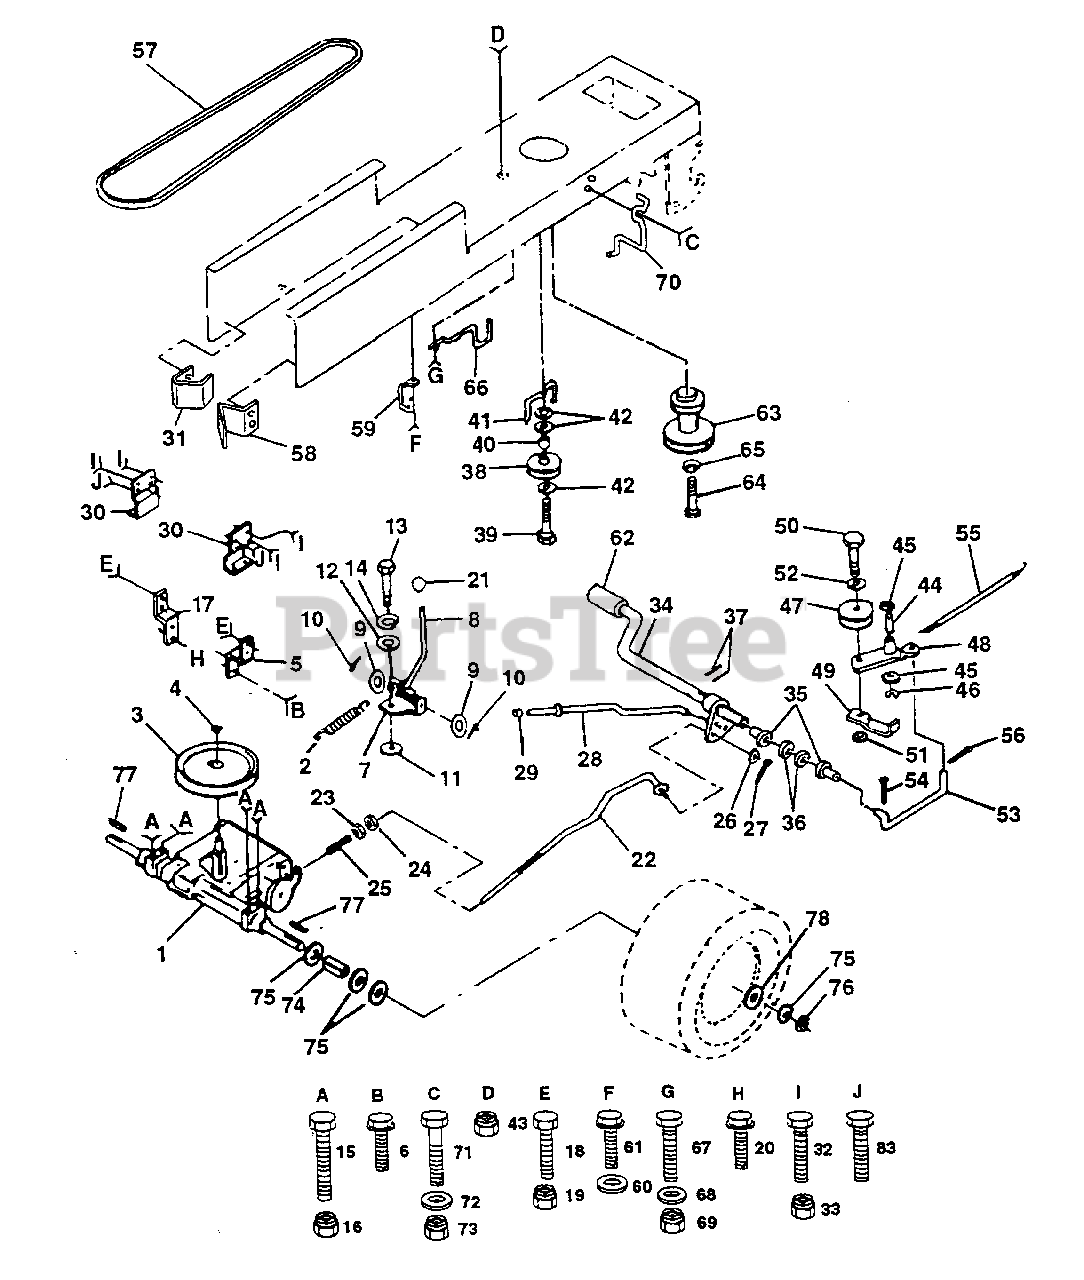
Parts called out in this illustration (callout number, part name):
1	Transaxle 6sp Dana LT Model No 4360-48 (AYP part number)
2	Spring Return Brake T/a Zinc (AYP part number)
3	Pulley Transaxle 18"tires (AYP part number)
4	Ring Retainer # 5100-62 (AYP part number)
5	Strap Torque 30 Degrees (AYP part number)
6	Screw Thdrol 5/16-18 X 3/4 TYT
7	Plate Rod Shift T/a (AYP part number)
8	Rod Shift Blk (AYP part number)
9	Washer 15/32 X 3/4 X 16 Ga (AYP part number)
10	Pin Cotter 1/8 X 1 Cad (AYP part number)
11	Washer Plate Shf 388 Sq Hole (AYP part number)
12	Washer 9/32 X 3/4 X 10 Ga (AYP part number)
13	Bolt Fin Hex 1/4-28unfx3/4 Gr8 (AYP part number)
14	Washer Lock Hvy Helical 1/4 (AYP part number)
15	Bolt Fin Hex 5/16-18uncx 2-1/2 (AYP part number)
16	Nut Crown Lock 5/16-18
17	Strap Torque 30 Degrees (AYP part number)
18	Bolt Fin Hex 3/8-16unc X 3/4 (AYP part number)
19	Nut Crownlock 3/8-16 Unc
20	Screw Thdrol 5/16-18 X 3/4 TYT
21	Knob Rd 1/2-13 Plstc Thds Blk (AYP part number)
22	Rod Brake LT/YT (AYP part number)
23	Nut Lock Hex W/wsh 3/8-16unc (AYP part number)
24	Nut Hex Jam 3/8-16 Unc (AYP part number)
25	Spring Rod Brake 2 00 Zinc (AYP part number)
26	Washer 13/32 X 13/16 X 16 Ga (AYP part number)
27	Pin Cotter 1/8 X 3/4 Cad (AYP part number)
28	Rod Brake Parking LT (AYP part number)
29	Cap Brake Parking Black (AYP part number)
30	Bracket Transmission (AYP part number)
31	Keeper Belt LH LT 14 Ga (AYP part number)
32	Bolt Fin Hex 5/16-18 unc X 3/4 (AYP part number)
33	Nut Crownlock 5/16-18 Unc
34	Shaft Asm Pedal Foot 1 930 (AYP part number)
35	Bearing Nylon Blk 629 Id (AYP part number)
36	Washer 21/32 X 1 X 16 Ga (AYP part number)
37	Pin Roll 3/16 X 1" (AYP part number)
38	Pulley Idler Flat (AYP part number)
39	Bolt Fin Hex 3/8-16unc X 2-3/4 (AYP part number)
40	Spacer Split 395 X 59 Bzp (AYP part number)
41	Keeper Belt Retainer (AYP part number)
42	Washer 13/32 X 13/16 X 12 Ga (AYP part number)
43	Nut Crownlock 3/8-16 Unc
44	Bearing Nyl 503 X 628 X 1 25 (AYP part number)
45	Washer Hardened (AYP part number)
46	Ring Klip #t5304-50 (AYP part number)
47	Pulley Idler V Groove Plastic
48	Bellcrank Asm Clutch (AYP part number)
49	Retainer Belt Style Spring (AYP part number)
50	Bolt Hex Hd 3/8-16unc X 1-1/2 (AYP part number)
51	Nut Crownlock 3/8-16 Unc
52	Washer 13/32 X 13/16 X 16 Ga (AYP part number)
53	Link Clutch 7 66 (AYP part number)
54	Pin Cotter 1/8 X 3/4 Cad (AYP part number)
55	Spring Return Clutch 6 75 (AYP part number)
56	Pin Cotter 1/8 X 3/4 Cad (AYP part number)
57	V-Belt Ground Drive 95 25 (AYP part number)
58	Keeper Belt RH LT Pnt/zinc 16g (AYP part number)
59	Keeper Belt Chassis Span Ctr (AYP part number)
60	Washer 13/32 X 13/16 X 12 Ga (AYP part number)
61	Screw Thdrol 3/8-16x3/4 Ty-tt (AYP part number)
62	Cover Pedal Blk Round (AYP part number)
63	Engine Pulley LT/YT (AYP part number)
64	Bolt Hex 7/16-20x4 Gr 5 (AYP part number)
65	Washer Lock Hvy HlcI Spr 7/16 (AYP part number)
66	Keeper Belt Engine LH LT (AYP part number)
67	Bolt Fin Hex 3/8-16unc X 1 (AYP part number)
68	Washer 13/32 X 13/16 X 12 Ga (AYP part number)
69	Nut Crownlock 3/8-16 Unc
70	Guide Belt Mower Drive RH (AYP part number)
71	Bolt Fin Hex 3/8-16unc X 1 (AYP part number)
72	Washer 13/32 X 1-1/4 X 12 Ga (AYP part number)
73	Nut Crownlock 3/8-16 Unc
74	Spacer Axle (AYP part number)
75	Washer 25/32 X 1 1/4 X 16 Ga (AYP part number)
76	E-ring #5133-75 (AYP part number)
77	Key Square 2 0 X 1845/ 1865 (AYP part number)
78	Washer 25/32 X 1-5/8 X 16 Ga (AYP part number)
83	Screw Thdrol 3/8-16 x 3/4 (AYP part number)
